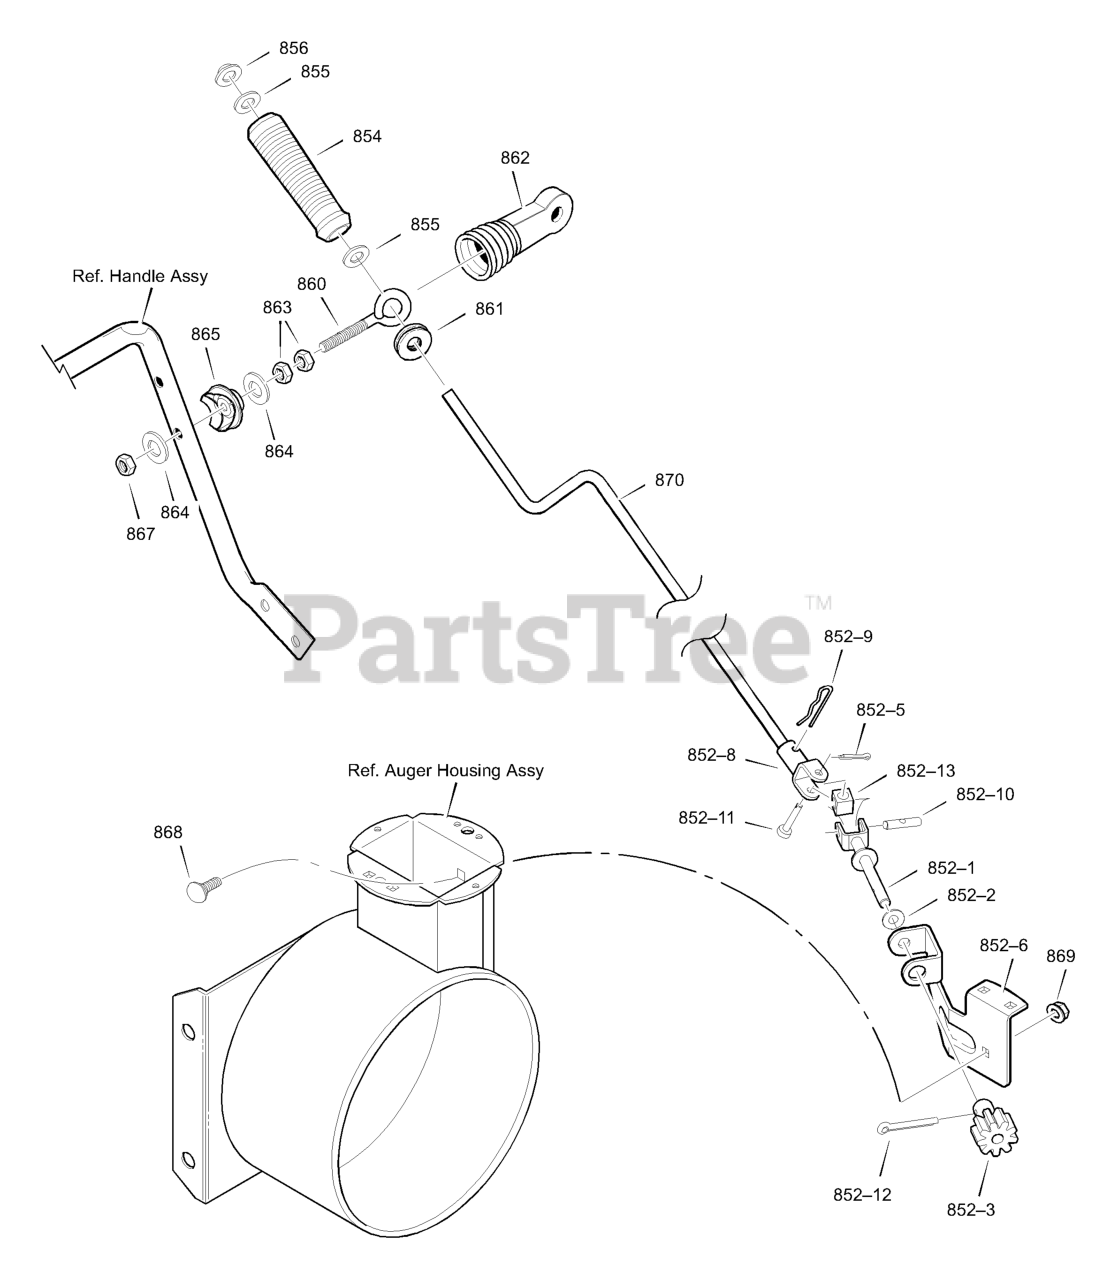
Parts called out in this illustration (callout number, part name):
852-1	ASSEMBLY, YOKE & ROD
852-2	WASHER, CURVED SPRING
852-3	GEAR, CHUTE ROTATION 9T
852-5	PIN, COTTER
852-6	BRACKET, GEAR MOUNT
852-7	PIN, COTTER
852-8	ASSEMBLY, YOKE ADAPTER YZ
852-9	PIN, HAIR
852-10	PIN, UNIVERSAL JOINT
852-11	PIN, CLEVIS
852-12	PIN, COTTER
852-13	HOUSING, UNIVERSAL
854	KNOB, SLEEVE
855	FLATWASHER
856	NUT, PUSH ON 3/8"
860	EYE BOLT 3/8-16X6.00
861	GROMMET, EYE BOLT
862	BOOT, EYE BOLT
863	NUT, 3/8-16 HEXJAM
864	FLATWASHER .406X.81X.066
865	ADAPTER, BOOT
866	WASHER, FLAT
867	NUT, 3/8-16 HEXNYL
868	BOLT, CARRIAGE 1/4-20 X 1.00
869	NUT, 1/4-20
870	CRANK, ASSY CHUTE
